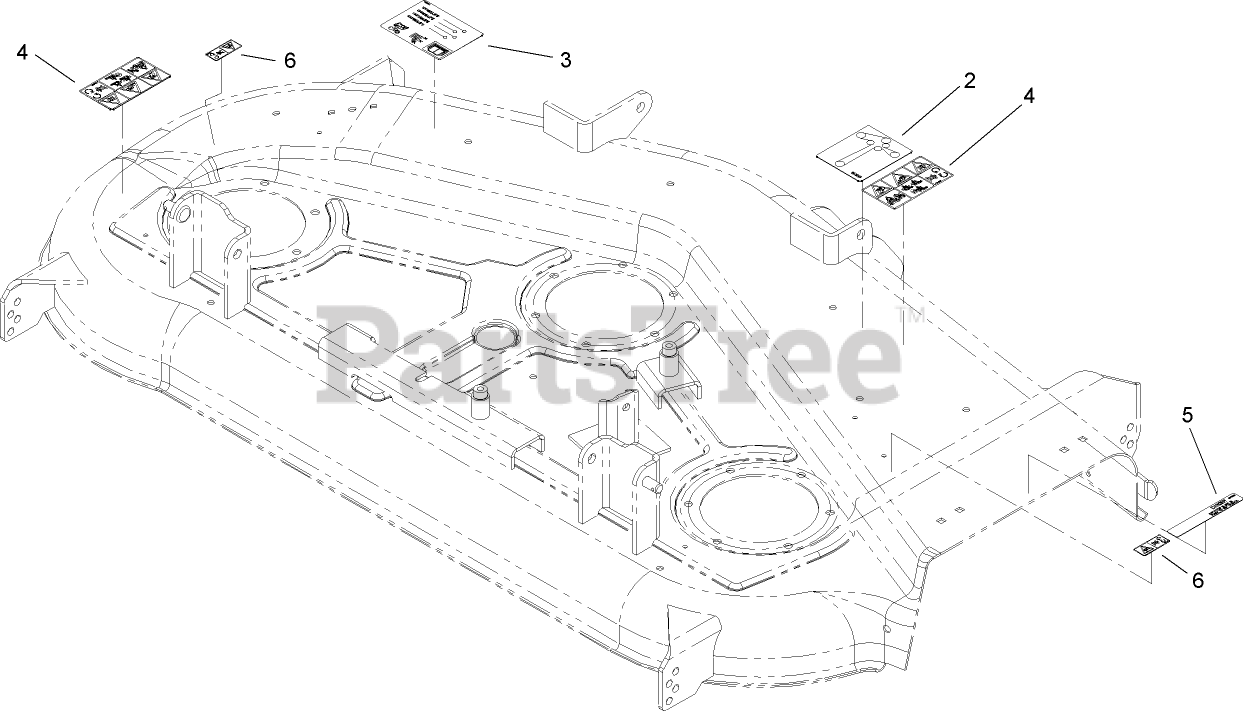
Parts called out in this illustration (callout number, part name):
2	DECAL-ROUTING, BELT
3	DECAL-SCALP, ANTI
4	DECAL-DANGER
5	DECAL-DANGER
6	DECAL-DANGER
